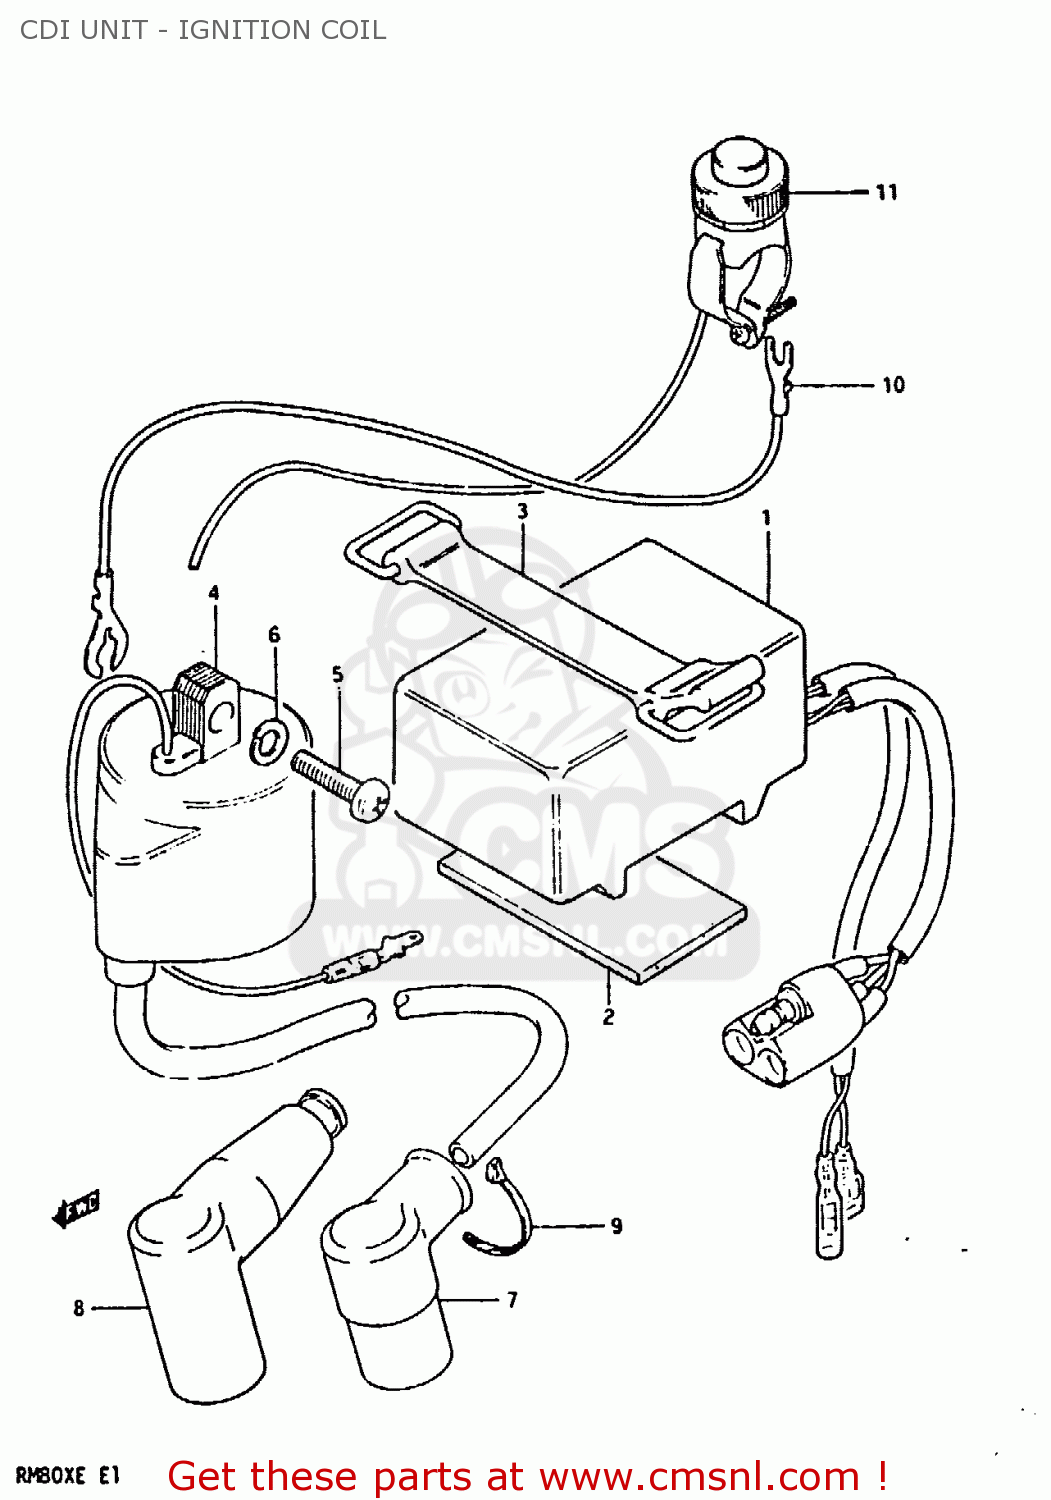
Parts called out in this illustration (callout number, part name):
1	CDI UNIT
2	PROTECTOR,BATTERY
3	BAND
4	COIL ASSEMBLY,IGNITION
5	SCREW
6	LOCK WASHER
7	CAP,SPARK PLUG
9	CLAMP
10	WIRE,ENGINE STOP EARTH
11	SWITCH ASSEMBLY
